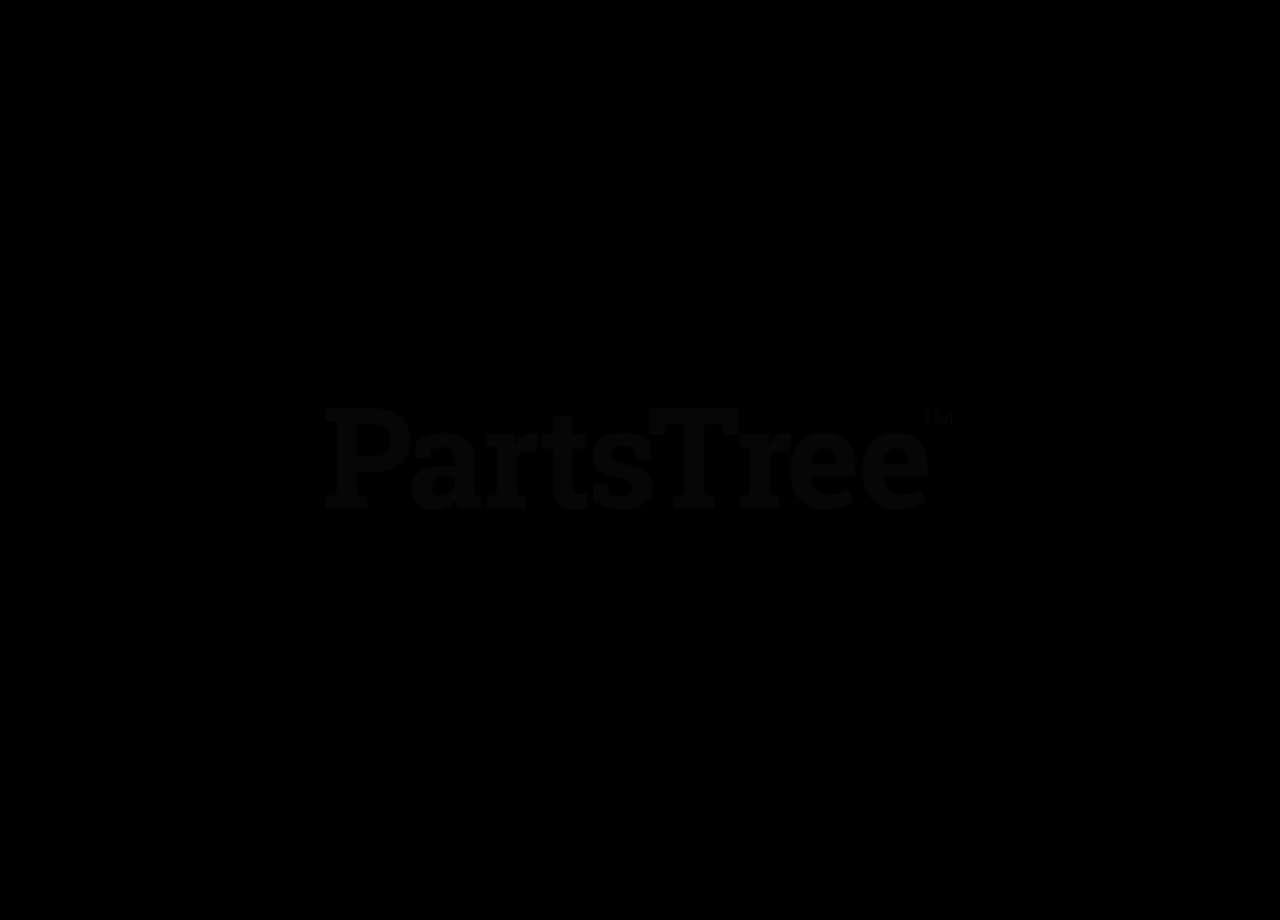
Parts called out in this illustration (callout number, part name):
1	Fork, Front
2	Bearing, Cone
3	Bearing, Cup 2.328 x .465
4	Bearing Seal 1.75 x 2.332 x .312
5	Spacer, 1.258 ID x 1.750 OD x .550
6	Spacer, Wheel
7	Wheel/Tire Assembly, 15 x 6-6, Smooth
8	Bolt, Hex .50-13 x 9.00 Grade 5
9	Nut, Locking Top Flange .50-13
10	Tire/Wheel Assembly, 24 x 11.50-12
11	Bolt, Lug .50-20 x 1.38
12	Wheel Motor, 18E (Counter Clockwise)
13	Bolt, Wheel Motor .50-13 x 2.75 Grade 8 (992215, 216)
14	Washer, Flat Steel, .812 x 2.00 x .148
15	Nut, Jam Center Lock .75-16
16	Cap, Dust
17	Bearing, 25mm I.D. x 52mm OD x 15mm
18	Bolt, Hex .31-18 x 1.50 Grade 8 EP30
19	Washer, Lock .31 x .078
20	Kit, Parking Brake Service
21	Nut, Locking Jam Patch 1.00-20
22	Bushing, .513 x .748 x 2.129 (992218)
